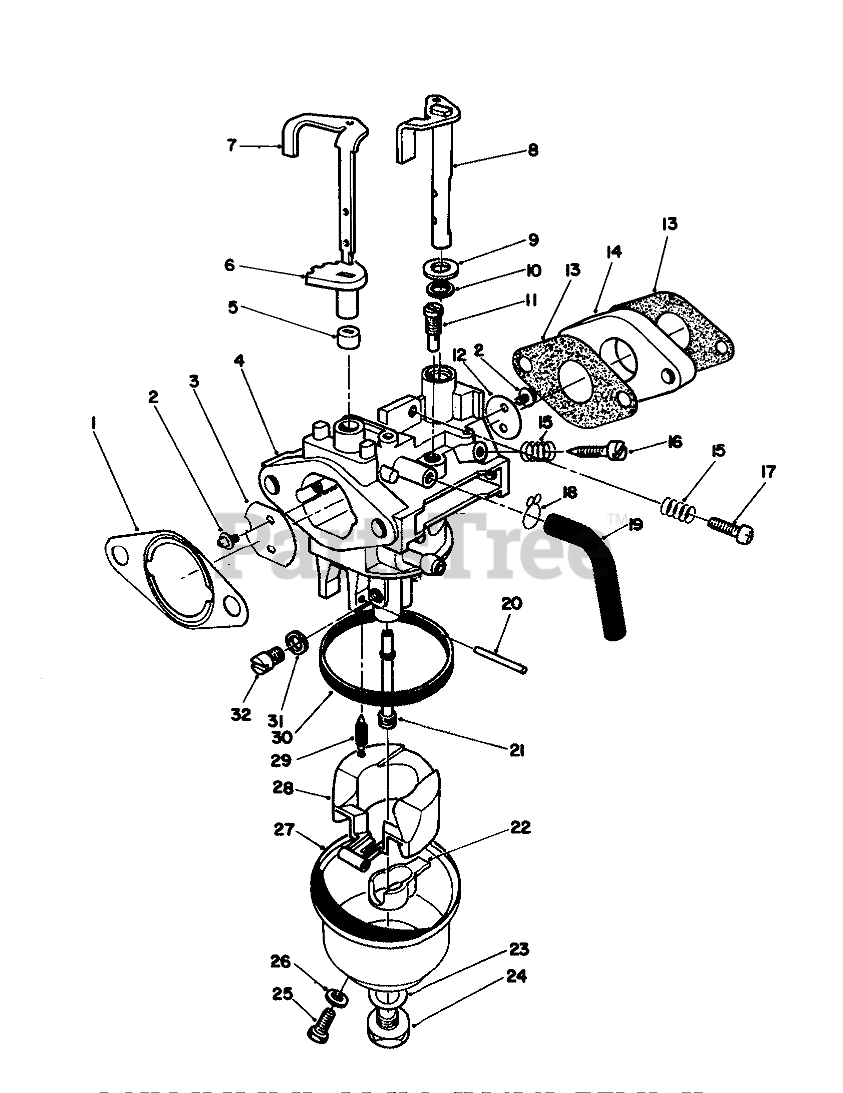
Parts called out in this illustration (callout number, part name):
1	GASKET F/W ENGINE
2	Screw
3	VALVE
4	Body-Carburetor
5	LOWER CHOKE RING
6	UPPER CHOKE RING
7	Shaft-Choke Valve
8	SHAFT
9	WASHER
10	Seal-Throttle Shaft
11	JET - PILOT
12	VALVE
13	GASKET INTAKE
14	INSULATOR - CARB.
15	SPRING-PILOT SCREW
16	ADJUSTER
17	SCREW
18	CLAMP
20	Pin
21	NOZZLE - MAIN
22	SPACER
23	GASKET
24	SCREW
25	SCREW
26	GASKET
28	FLOAT
29	NEEDLE
30	FLOAT BOWL GASKET
31	SPACER
32	JET - MAIN
